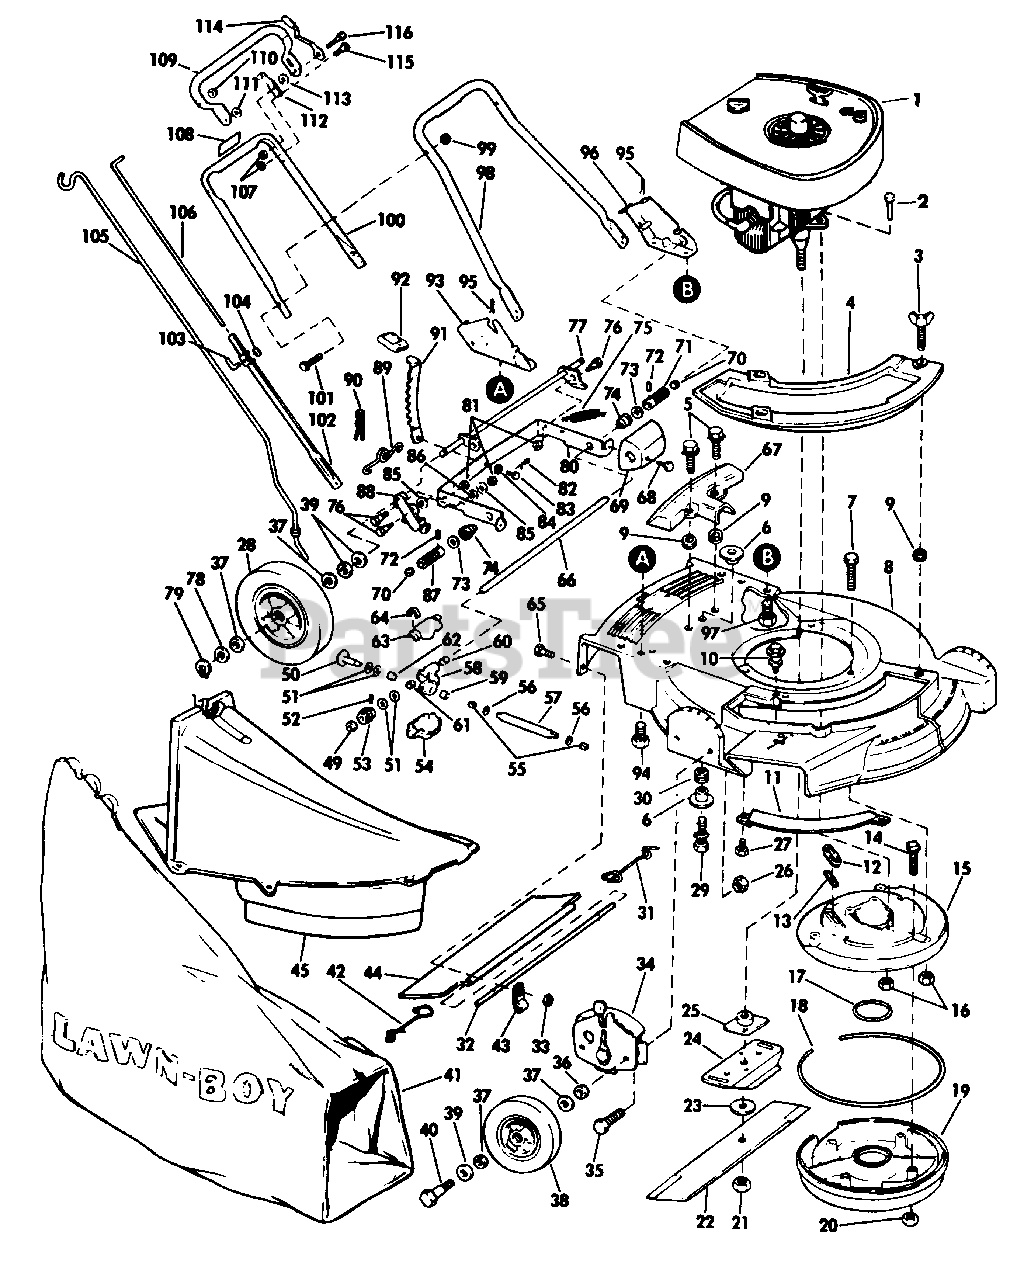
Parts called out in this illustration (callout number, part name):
2	Screw-Crankcase to Muffler Plate
3	Wing Screw
4	Cover Plate
5	Sems Screw-Drive Cover Mounting
6	Spacer-Flanged
7	Screw-Muffler Plate to Housing
8	Housing-21"
9	Grommet
10	Screw
11	Toe Bar
12	Sleeve-Muffler Gasket
13	Gasket-Exhaust
14	Screw-Muffler to Muffler Plate
15	Muffler Plate
16	Nut
17	Gasket-Muffler (inside)
18	Gasket-Muffler (outside)
19	Muffler Cover
20	Nut-Muffler to Muffler Plate
21	Nut-Blade
22	Blade
23	Washer-Blade
24	Stiffener-Blade
25	Collar & Plate Assembly
26	Nut
27	Screw
28	Wheel-Rear
29	Sems Screw
30	Grommet
31	Spring-L.H.
32	Rod
33	Nut
34	Height Adjustment Assembly
35	Screw
36	Washer
37	Washer Felt
38	Front Wheel
39	Washer
40	Screw
41	Grass Bag
42	Spring-R.H.
43	Clamp
45	Chute Assembly
49	Washer Felt
50	Gear Driver
51	Washer-Thrust
52	Roll Pin
53	Gear Drive
54	Cover-Gear Bottom
55	Bushing
56	"O" Ring
57	Tube
58	Bracket & Bearing Assembly
59	Needle Bearing-Sealed
60	Needle Bearing-Sealed
61	Needle Bearing
62	Needle Bearing
63	Cover-Gear Top
64	Clamp
65	Screw
66	Shaft
67	Cover-Drive
68	Screw
69	Guard-Roller
70	Plug
71	Drive Roller-L.H.
72	Pin-Spirol
73	Washer
74	Sleeve & Bearing Assembly
75	Spring
76	Bolt-Shoulder
77	Axle Assembly
78	Washer
79	Retaining Ring
80	Bracket
81	Nut
82	Cotter Pin
83	Pin
84	Washer
85	Washer
86	Washer
87	Drive Roller-R.H.
88	Clutch
89	Spring
90	Hairpin
91	Lever
92	Knob
93	Bracket-Handle-R.H.
94	Screw-Handle Bracket
95	Clip
96	Bracket-Handle-L.H.
97	Screw-Handle Bracket
98	Handle-Lower
99	Nut
100	Handle-Center
101	Screw
102	Control Lever Assembly
103	Screw
104	Nut
105	Rod-Grass Bag
106	Control Rod
107	Nut
108	Decal
109	Handle & Grip Assembly
110	Palnut
111	Washer
112	Bracket
113	Washer
114	Spring-Lockout
115	Screw-Stop
